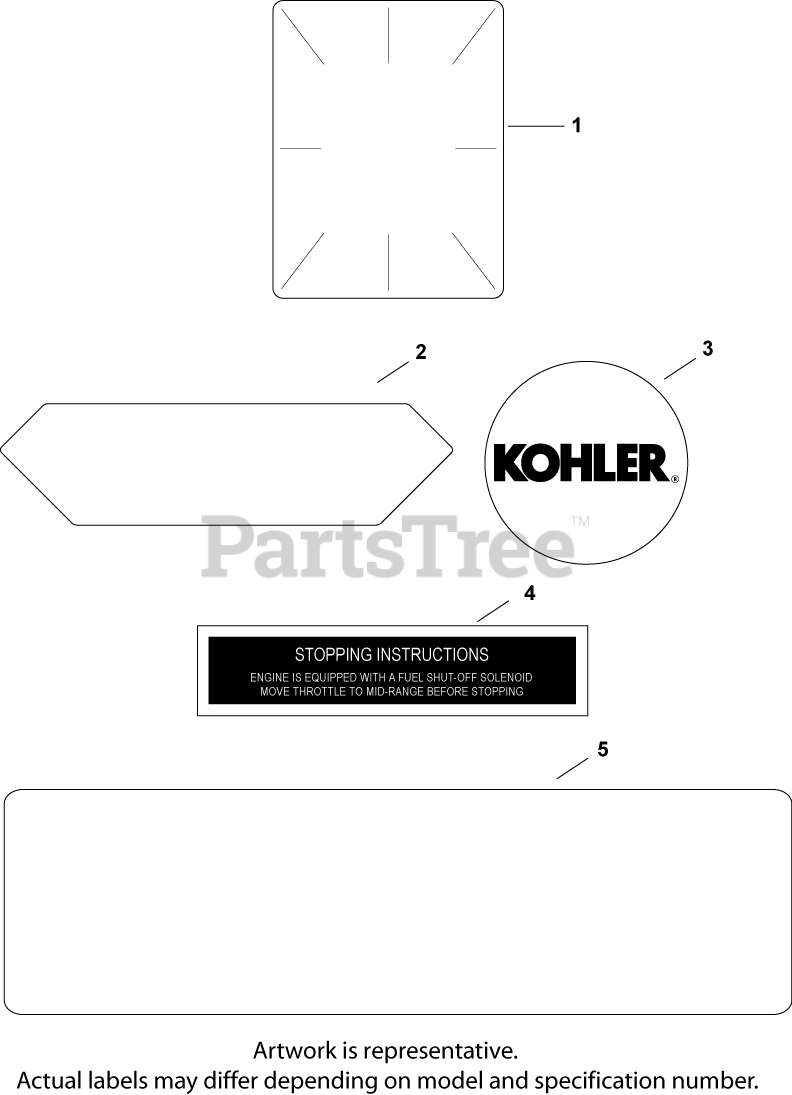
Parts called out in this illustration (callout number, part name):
1	DECAL, CLEAR LAMINATE USE 25 113 70-S
2	DECAL, AIR FILTER COVER - DISC.
3	DECAL, GRASS SCREEN USE 24 113 499-S
4	DECAL, STOPPING INSTRUCTION
5	DECAL, 22 HP
